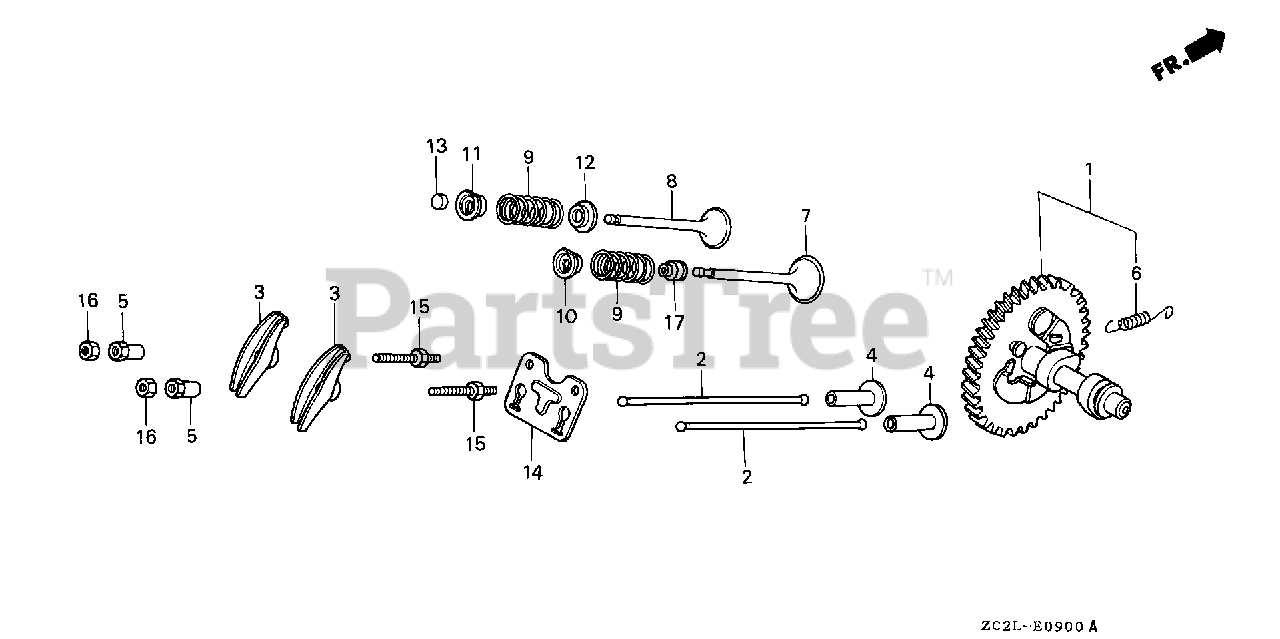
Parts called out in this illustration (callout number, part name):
1	CAMSHAFT ASSY.
3	ARM, VALVE ROCKER
4	LIFTER, VALVE
5	PIVOT, ROCKER ARM
6	SPRING, WEIGHT RETURN
7	VALVE, IN.
8	VALVE, EX.
9	SPRING, VALVE
10	RETAINER, IN. VALVE SPRING
11	RETAINER, EX. VALVE SPRING
12	SEAT, VALVE SPRING
13	ROTATOR, VALVE
14	GUIDE, PUSH ROD
15	BOLT, PIVOT (8MM)
16	NUT, PIVOT ADJUSTING
17	SEAL, VALVE STEM
